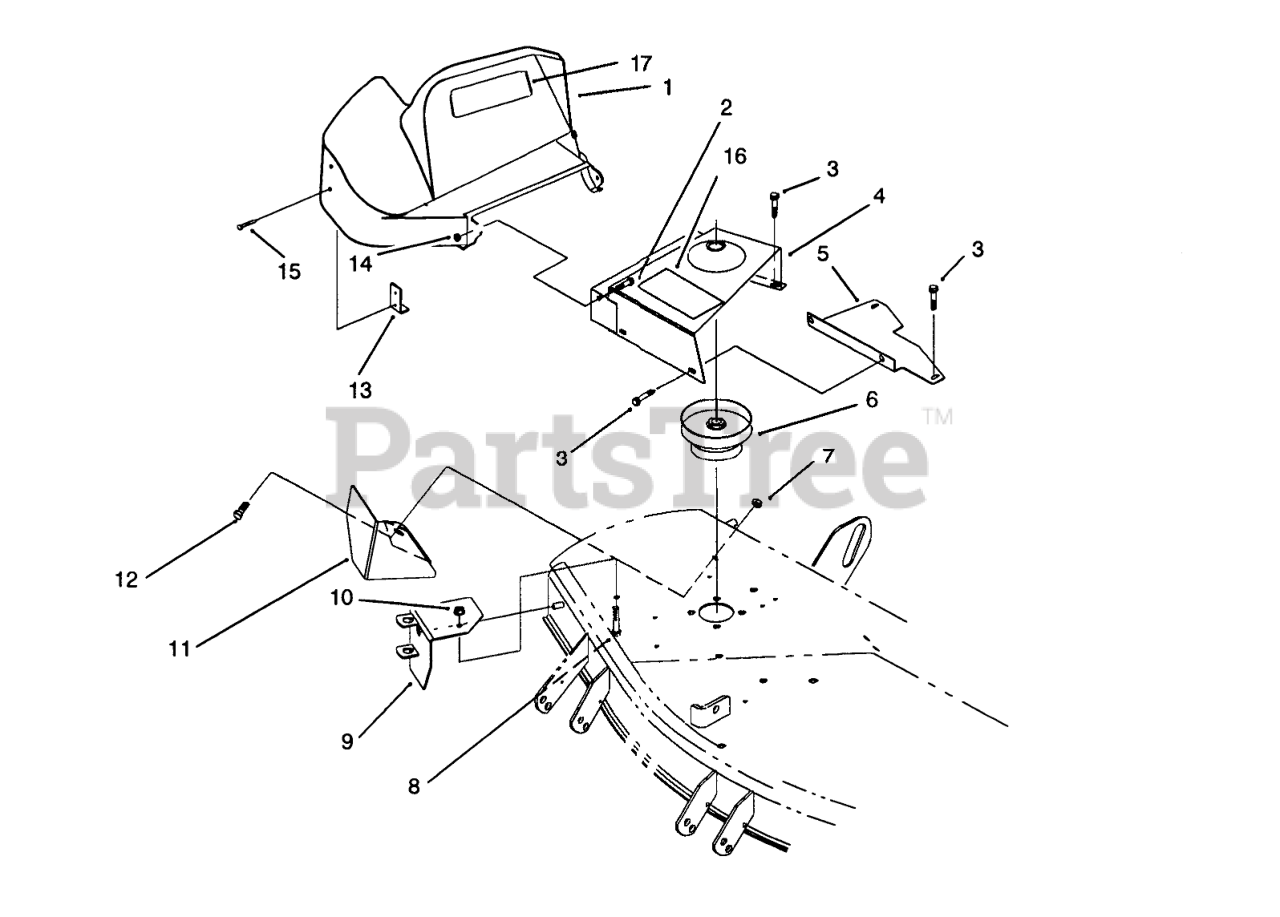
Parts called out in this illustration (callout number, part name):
1	Belt Shield Assembly (Incl. Ref. #17)
2	SCREW-HH
3	Bolt
4	42" Inner Shield Assembly (Incl. Ref. #16)
5	42" ADAPTOR SHIELD B
6	PULLEY
7	NUT-LOCK, NI
8	SCREW-HH
9	PIVOT SUPPORT ASM
10	NUT-HF
11	42" DEFLECTOR B
12	SCREW-CARR
13	BRACKET-SUPPORT, SHIELD
14	NUT-LOCK, NI
15	RIVET-POP
16	DECAL-DANGER, THROWN OBJECT
17	DECAL - DANGER
